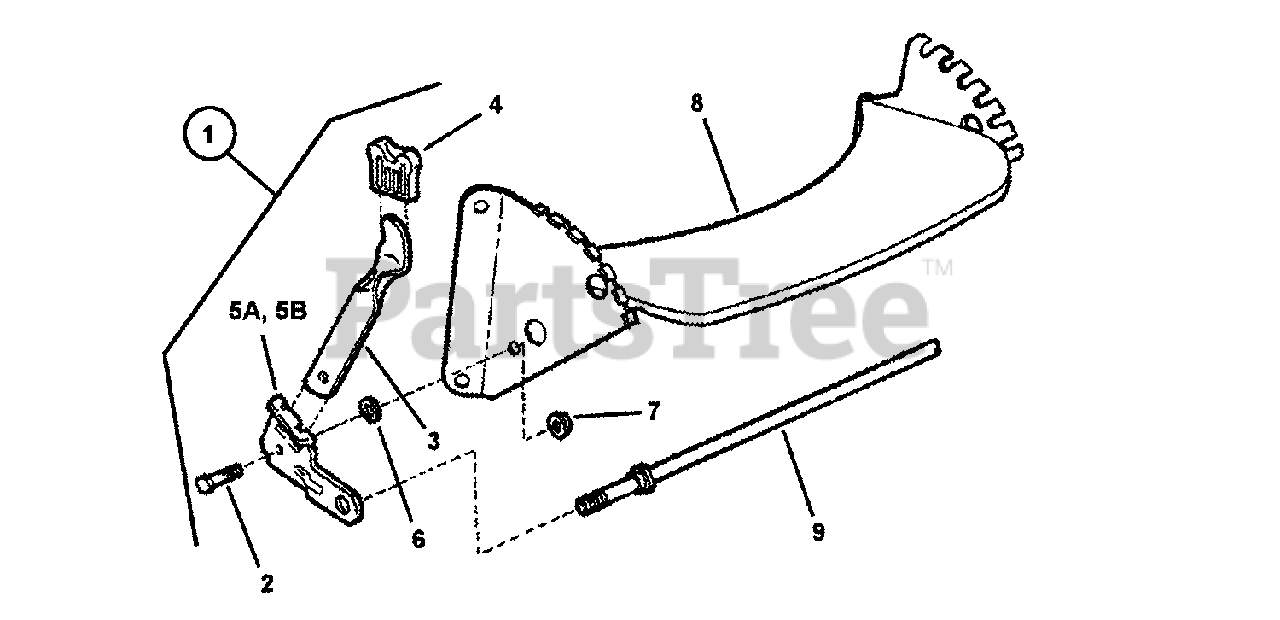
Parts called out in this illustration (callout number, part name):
1	ASSEMBLY, Right Wheel Arm
2	BOLT, 5/16-18 Hex Washer Face Shoulder
3	LATCH, Height
4	GRIP, Latch
5A	ARM, Right Wheel (Round Hole)
6	RETAINER, 5/16" Bolt (Black)
7	NUT, 5/16-18 Hex Flange Lock
8	WELDMENT, Front Wheel Bracket
9	AXLE
